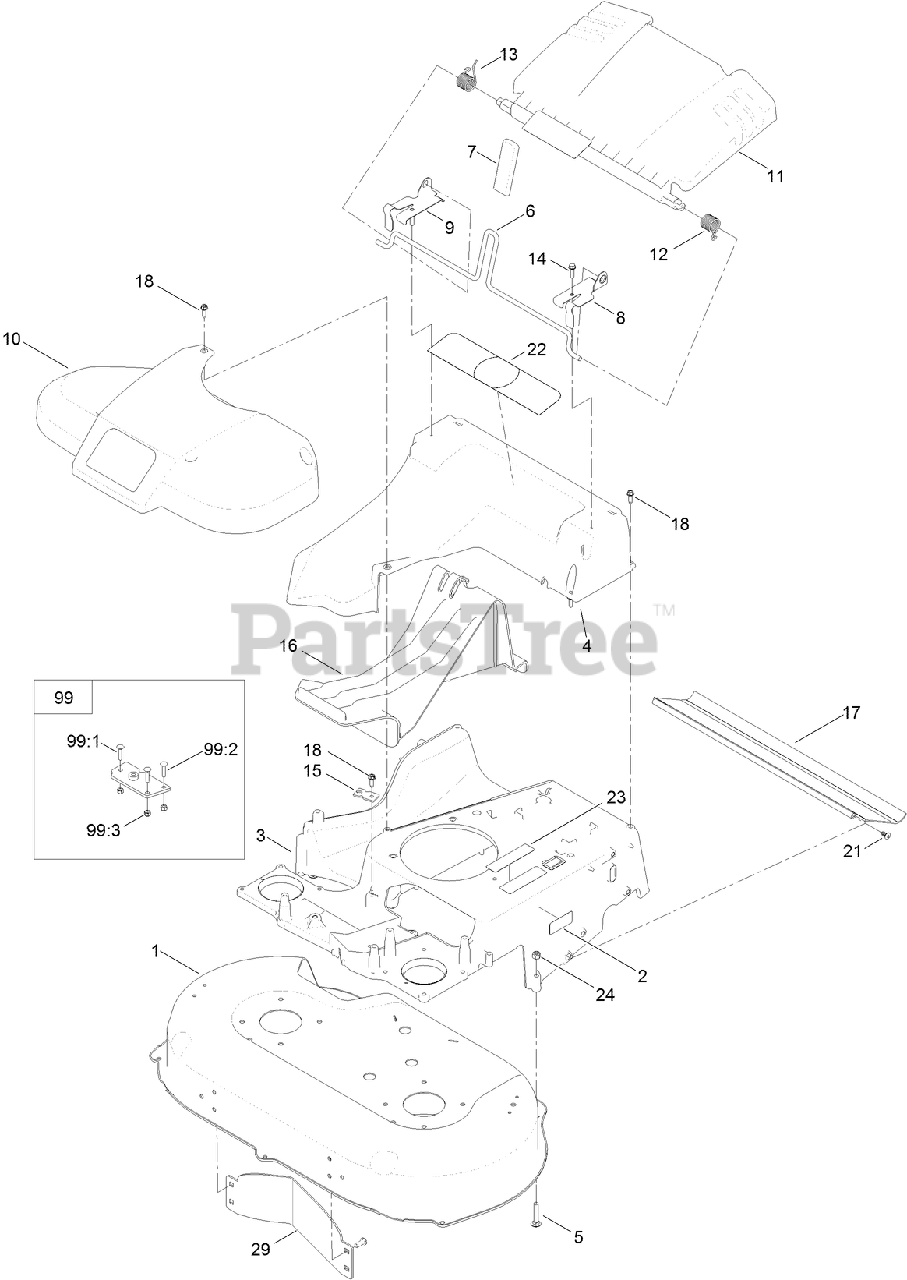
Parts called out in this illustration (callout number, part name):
2	DECAL-LOCATION, SERVICE DEALER
5	BOLT-CAR
6	ROD-RELEASE, HANDLE
7	GRIP-LEVER
8	BRACKET-DOOR, LH
9	BRACKET-DOOR, RH
10	BELT COVER ASM
11	REAR DEFLECTOR ASM
12	SPRING-TORSION
13	SPRING-TORSION
14	SCREW-HWH
16	PLUG-MULCH
17	SHIELD-TRAILING
18	SCREW-HWHTF
21	SCREW-PTH
22	DECAL-POSITION, HANDLE
23	DECAL-ARRESTER, SPARK
24	NUT-LOCK, NI
29	BAFFLE-CONTROL
99	FRAME PLATE KIT
99:1	PLATE-FRAME
99:2	SCREW-CARR
99:3	NUT-LOCK, NI
